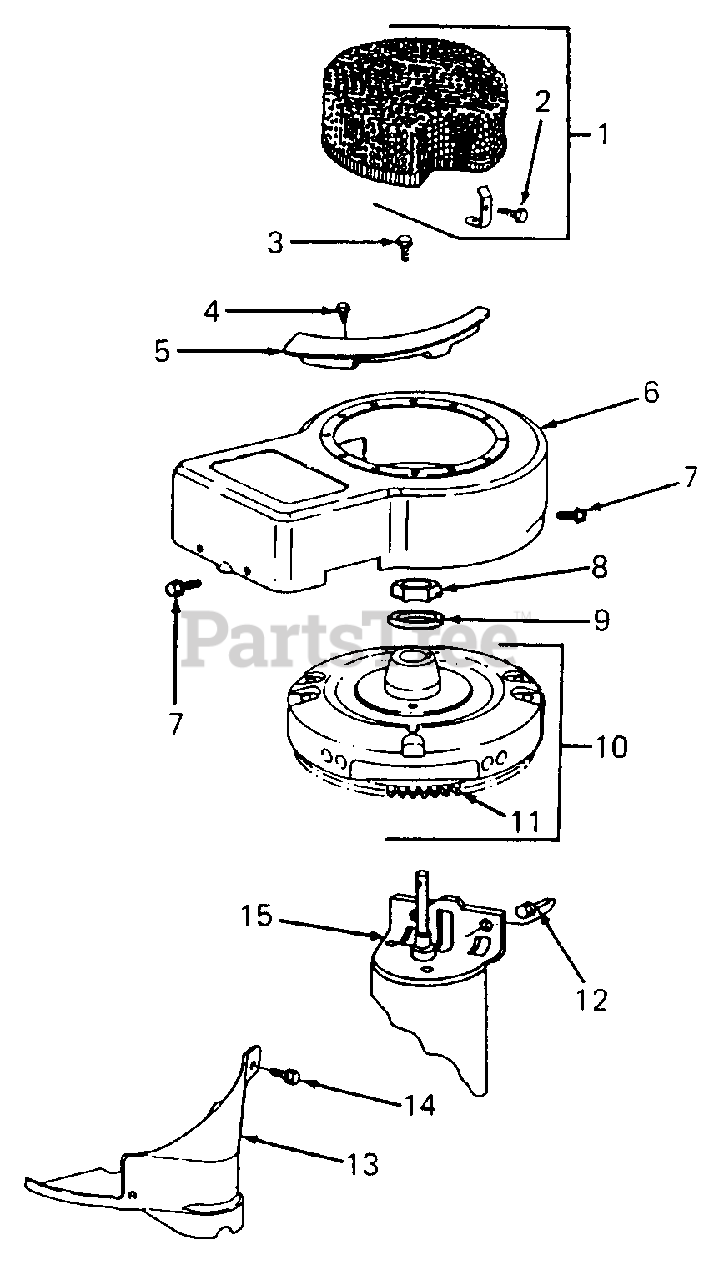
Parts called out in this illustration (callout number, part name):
1	Guard, Debris
2	Screw, Hex Washer Head
3	Screw, Hex Head Sem
4	Screw, Hex Head
5	Guard, Flywheel
6	Housing, Blower
7	Screw, Blower Housing Mtg Sem
8	Nut, Hex
9	Washer, Spring
10	Flywheel & Ring Gear Assy, Magneto
11	Gear, Ring
12	Screw, Sem Starter Mtg
13	Cover, Starter
14	Screw, Sem
15	See Starter Motor
